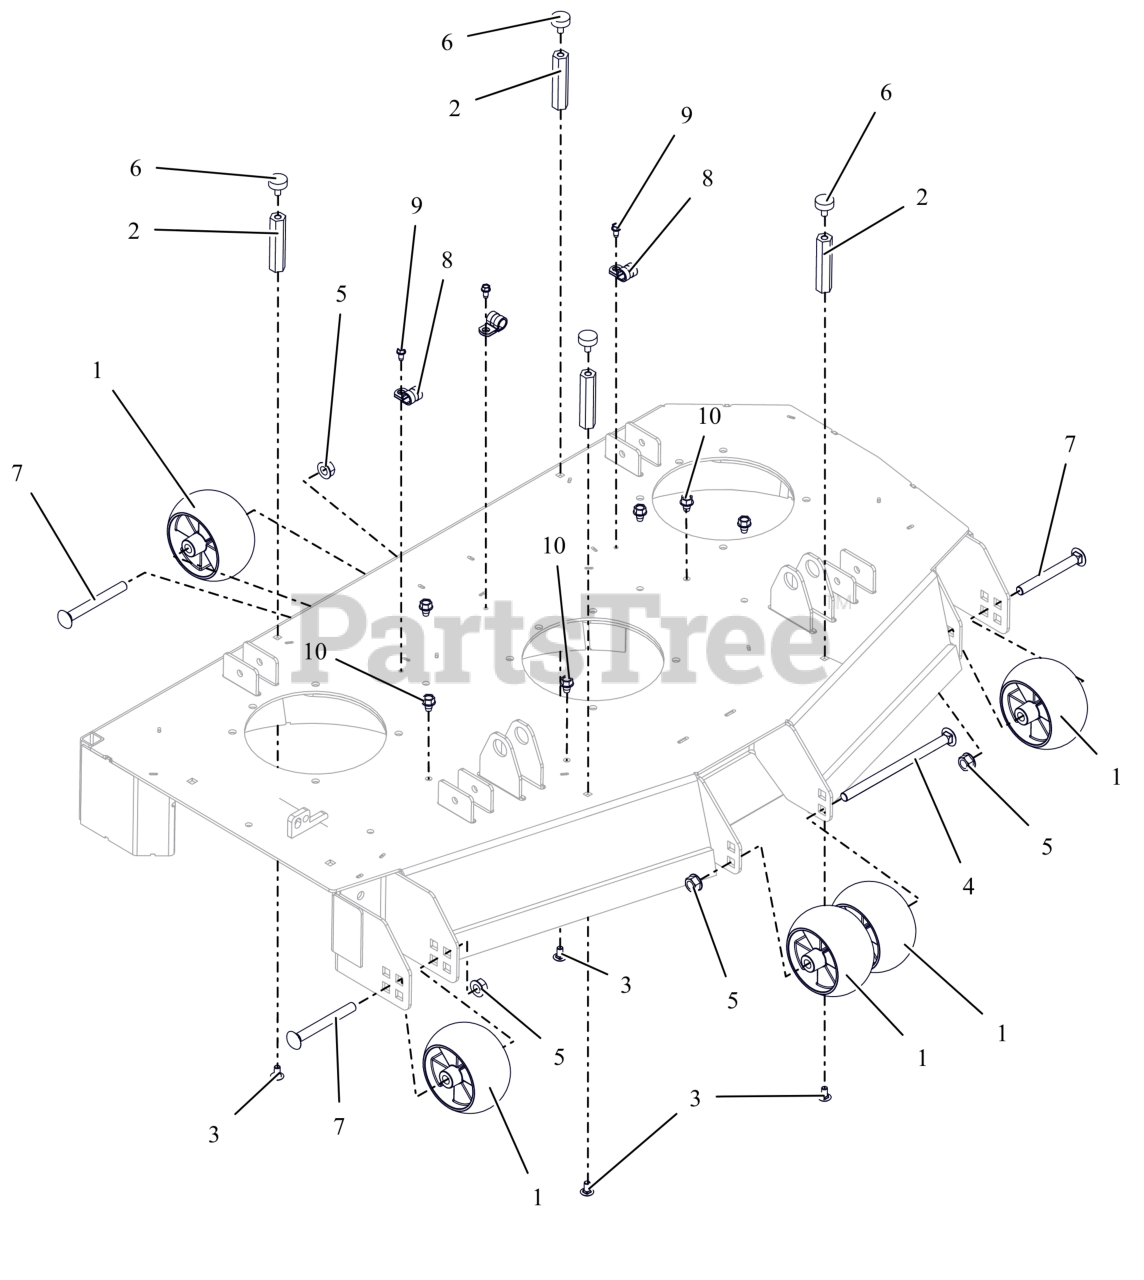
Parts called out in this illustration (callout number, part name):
1	WHEEL, ANTI SCALP - 5X3 CTR W/RIBS
2	NUT, COUPLING .312-18 X 3.375
3	BTL,RHSSN .313-18 X 0.625 G5 ZCC
4	BLT,RHSN .50-13X8.00 G5 ZCC NS
5	NUT-LK-CTR-FLG .500-13 GG ZCC
6	BUMPER, RUBBER
7	BLT,RHNS .50-13X4.50 G5 ZCC NS
8	CLAMP, CUSHIONED STEEL
9	SCR-TAP .25-20X.50 HWH ZCC
10	SCR,TAP .375-16X.50 HWH TR ZCC
